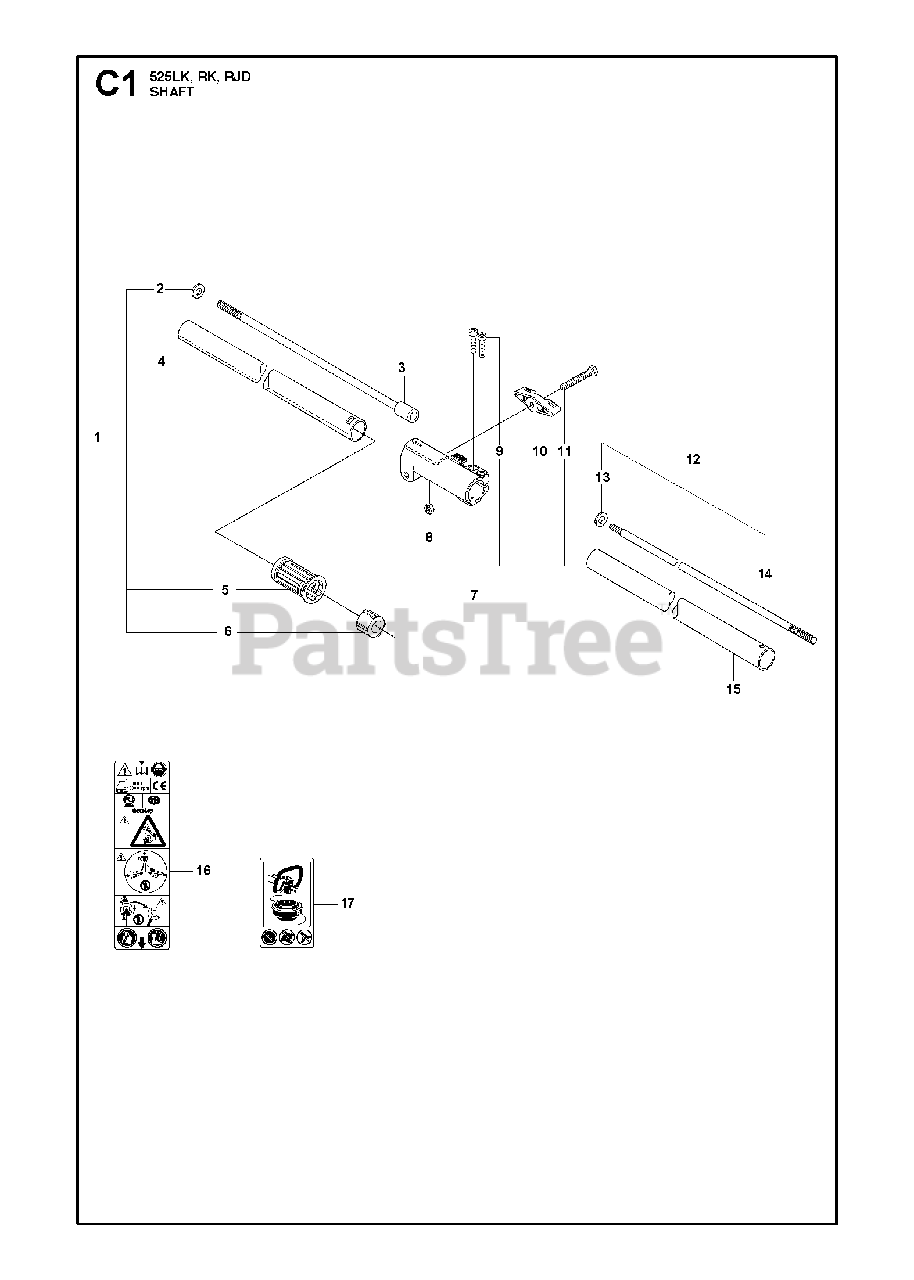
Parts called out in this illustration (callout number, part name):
2	WASHER
3	SHAFT LOWER
5	PLUG
6	BUSHING
7	CLAMPING SLEEVE ASSY
8	NUT
9	SCREW
10	KNOB CLAMPING SLEEVE
11	SCREW
12	DRIVE SHAFT COMPL
13	WASHER
14	DRIVE SHAFT
16	WARNING DECAL
17	DECAL WARNING "NO BLADES"
